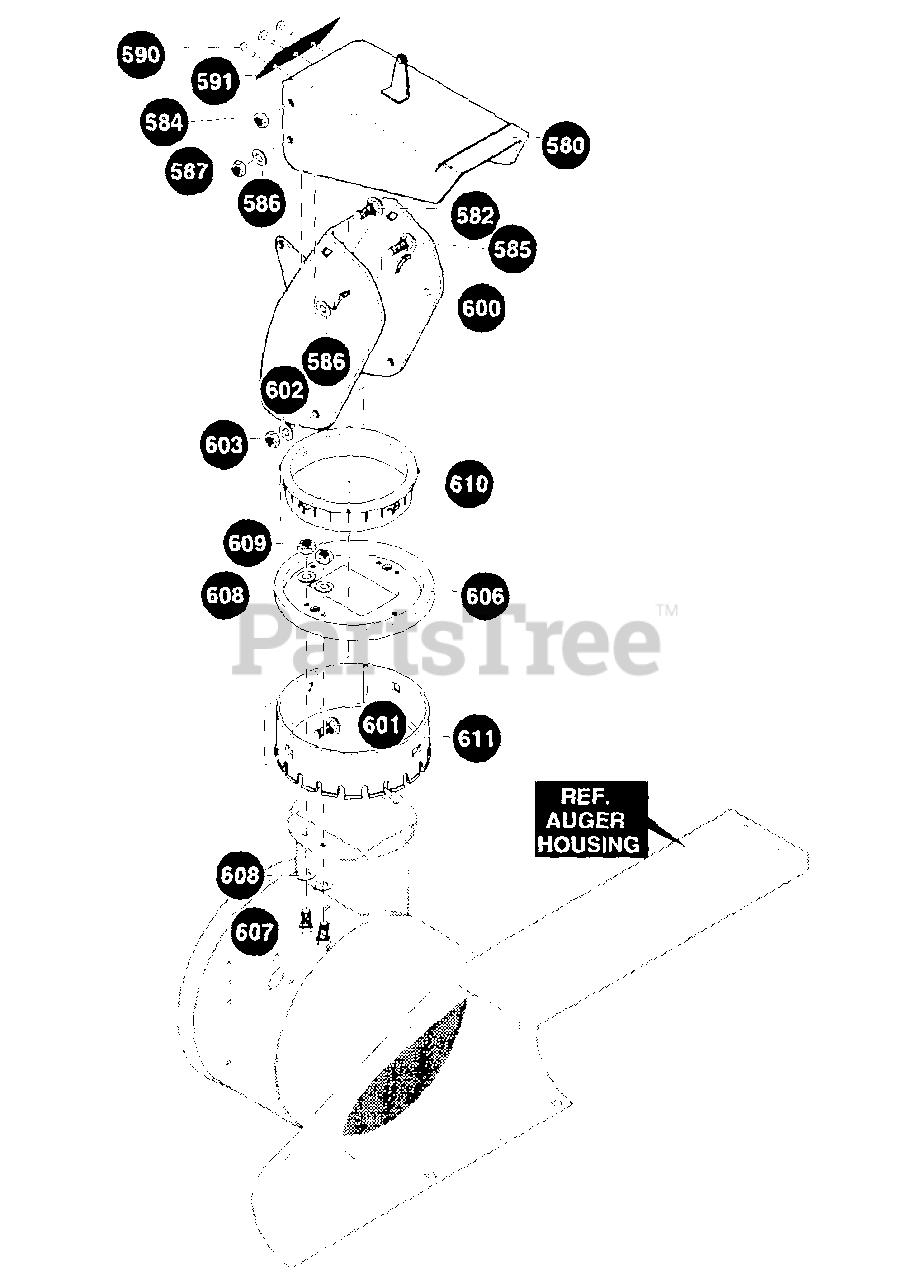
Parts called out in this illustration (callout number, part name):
580	CHUTE,UPPER
582	SCREW, 5/16-18 X .75
584	NUT, 5/16-18 HEXNYL
585	SCREW, 5/16-18 X .75
586	WASHER, PLASTIC
587	NUT, 5/16-18 HEXNYL
590	RIVET, POP
591	SKIRT, CHUTE
600	CHUTE, LOWER
601	BOLT, 5/16-18 X 1.00
602	FLATWASHER .344 X .69 X 065
603	NUT, 5/16-18 HEXNYL
606	COLLAR, CH
607	SCREW, 1/4-20 X .75
608	FLATWASHER .281 X 63 X .065
609	NUT, 1/4-20
610	RETAINER, RING INNER
611	RETAINER, RING OUTER
